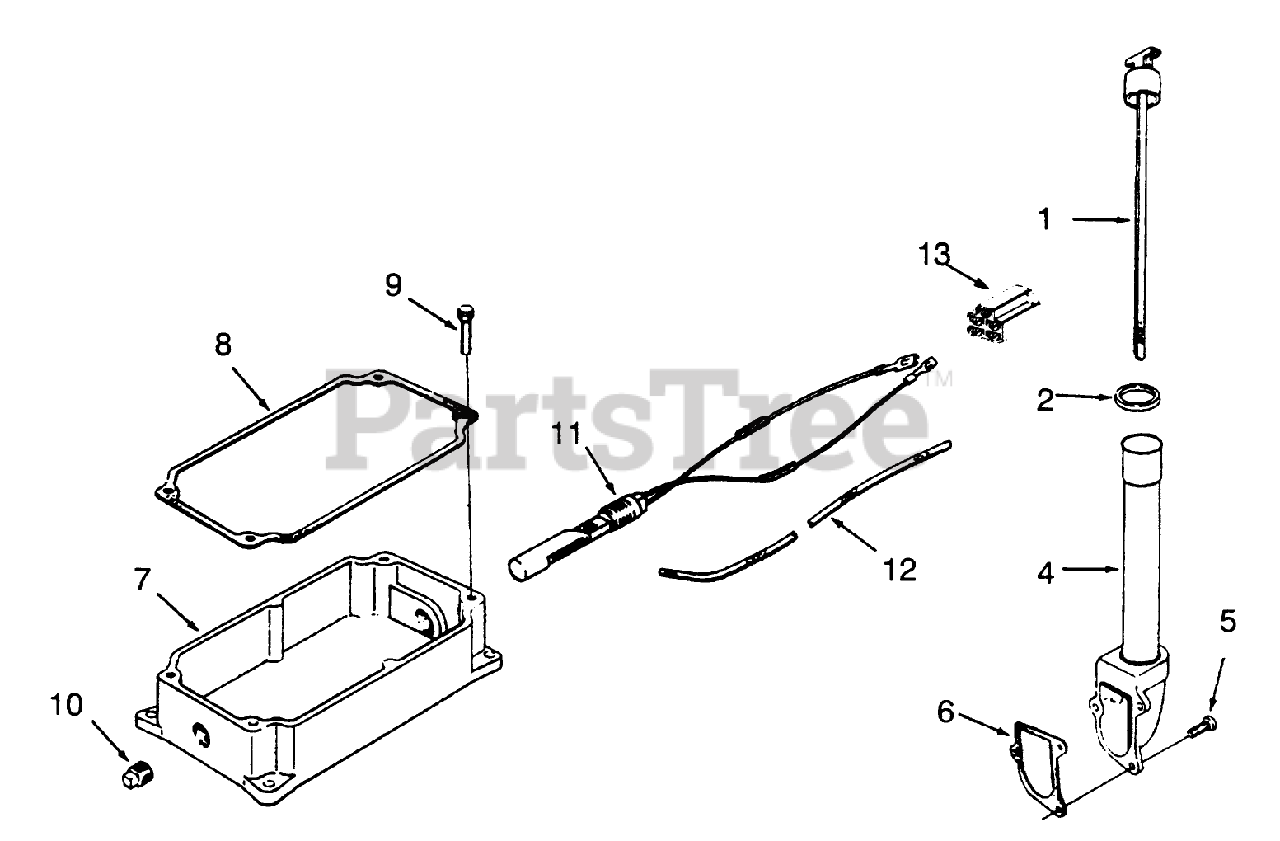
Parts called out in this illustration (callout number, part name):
1	KOHLER 47-038-27
2	KOHLER 41-153-01
4	KOHLER 47-029-06
5	KOHLER X-131-2
6	KOHLER 237064
7	KOHLER 45-199-05
8	KOHLER 235057
9	KOHLER X-159-3
10	KOHLER X-75-10
12	KOHLER 25-431-02
13	KOHLER 48-155-01
